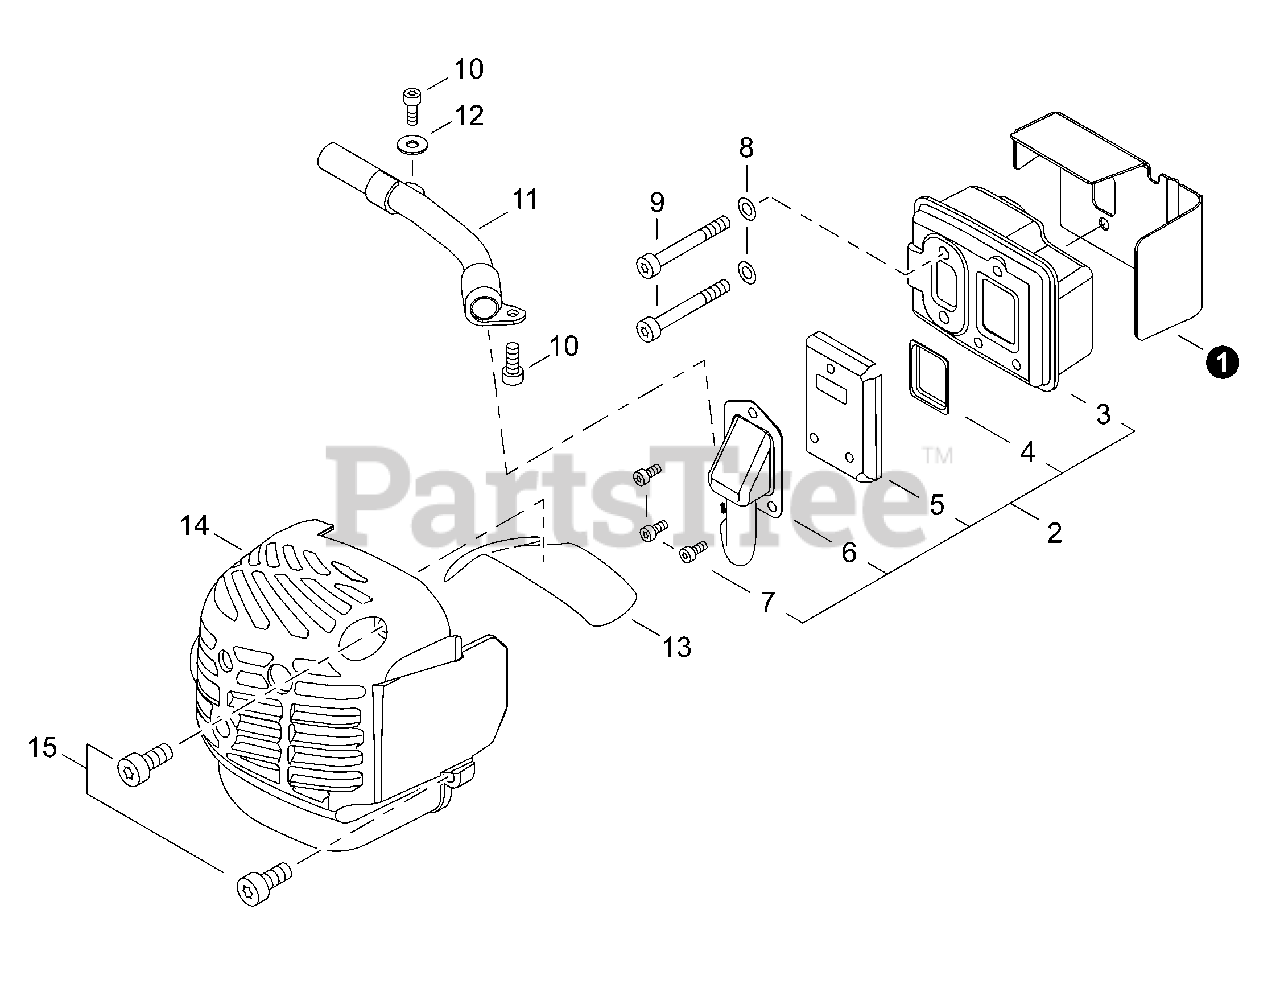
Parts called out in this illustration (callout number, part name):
1	HEAT SHIELD, EXHAUST
2	MUFFLER ASSY
3	MUFFLER
4	SCREEN, SPARK ARRESTER
5	GASKET, EXHAUST
6	GUIDE, EXHAUST
7	BOLT, TORX 4×8
8	WASHER 5.5×12×0.8
9	BOLT, TORX 5×55
10	BOLT, TORX 5×10
11	GUIDE, EXHAUST
12	WASHER 5
13	PLATE, INSULATOR
14	COVER, MUFFLER
15	BOLT, TORX 5×16
